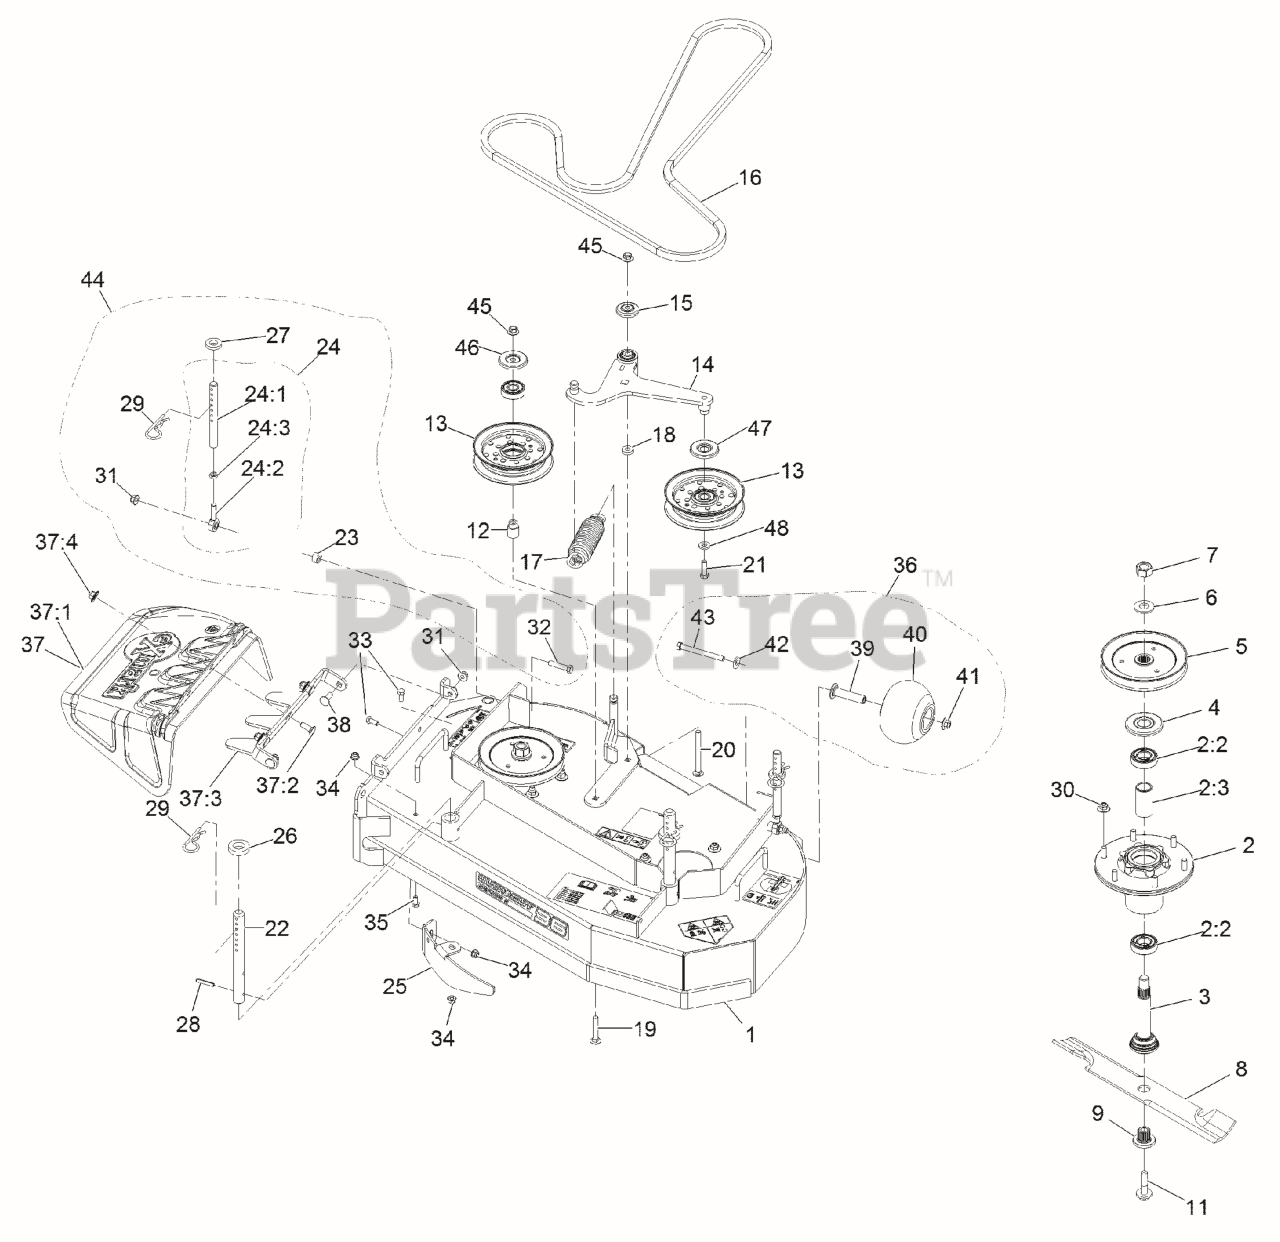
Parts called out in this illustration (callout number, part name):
1	ASM, DECK W/ DECALS, 36"
2	ASM-CUTTER HSG WITH BEARINGS
2:2	BEARING-BALL
2:3	SPACER-BEARING
3	ASM-SPINDLE AND SEAL
4	GUARD,BEARING TOP .989
5	SHEAVE,BLADE DRIVE 6.50
7	NUT-HEX
9	BUSHING,SPLINED
11	SCREW,SEMS 1/2-20 X 2.19
12	BUSHING-IDLER
14	ASM-ARM, IDLER
15	GUARD-TOP
16	BELT-5V
17	SPRING-EXTENSION
18	SPACER
19	Bolt-Carriage 3/8-16 X 2 1/4
20	SCREW-CARR
21	SCREW-HFH
22	ROD,DECK SUPPORT
24:1	LINK,SUPPORT
24:2	BALLJOINT
24:3	NUT-HJ
25	BAFFLE, DOGLEG
26	SPACER-DECK SUPPORT
29	PIN,HAIR COTTER
30	Nut-Nyloc 3/8-16 Flg
31	NUT-HF, NI
32	SCREW-HH
33	SCREW-HH
34	NUT-HF, NI
35	SCREW-HH
36	KIT, ANTI-SCALP ROLLER
37	ASM, DISCHARGE CHUTE
37:1	CHUTE,DISCHARGE
37:2	BRACKET, DISCHARGE CHUTE
37:3	SCREW-CARR
37:4	Nut-Nyloc 3/8-16 Flg
38	SCREW-CARR
39	AXLE, ROLLER
40	ROLLER-SCALP, ANTI
41	Nut-Nyloc 3/8-16 Flg
42	WASHER-BELLEVILLE
43	SCREW-HH 3/8-16 X 3 3/4 GR 8
44	KIT,SUPPORT LINK W/PIN
